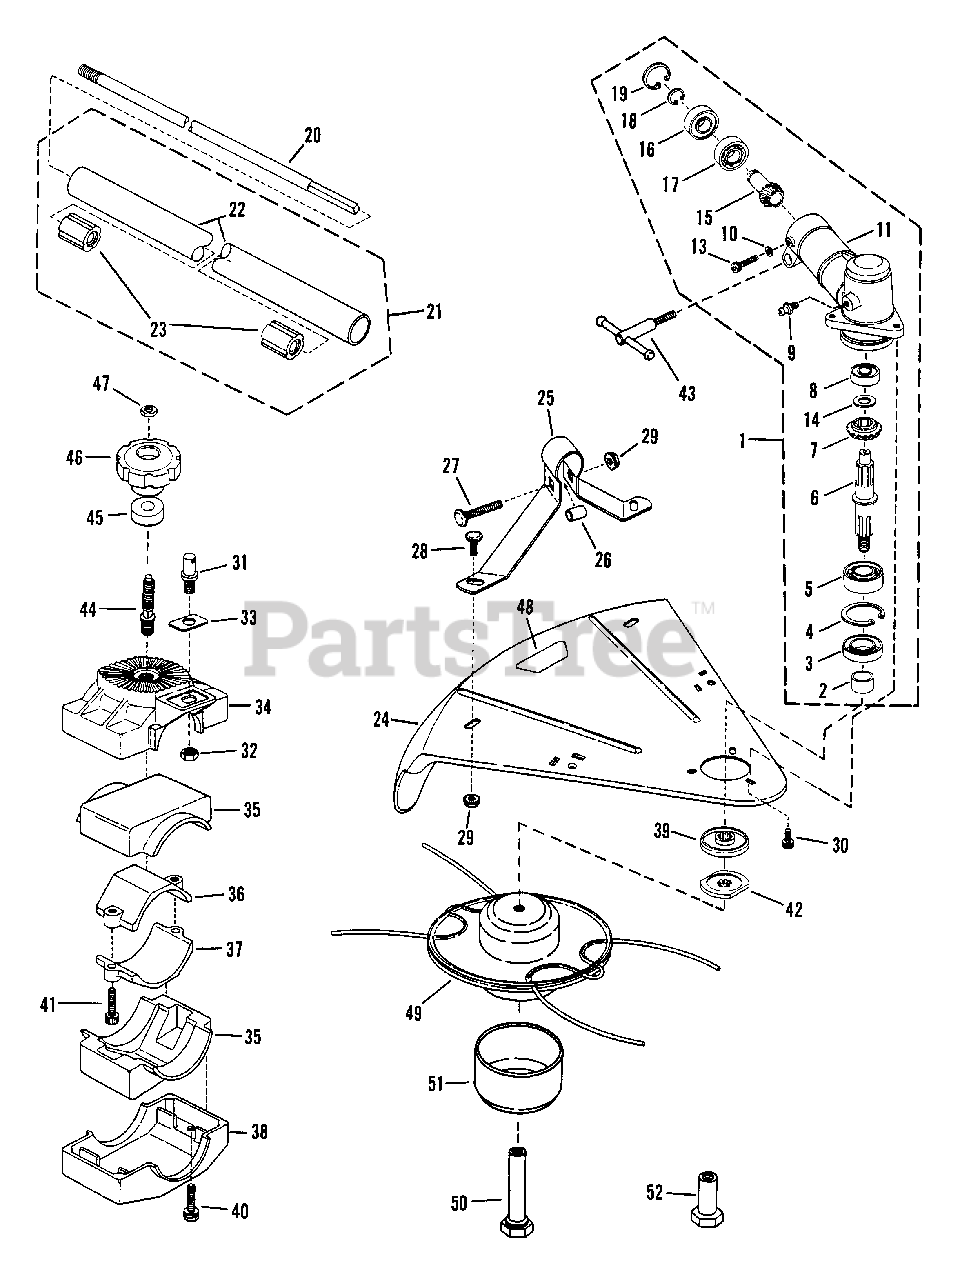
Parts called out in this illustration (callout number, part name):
1	ASSEMBLY, Gear Head
2	SLEEVE, Spline
3	SEAL, Oil
4	RING, Snap 35mm
5	BEARING
6	SHAFT, Spline
7	GEAR, Bevel
8	BEARING
9	FITTING, Lube
11	CASE, Gear
12	BOLT, M6x20mm Socket
13	BOLT, M5x15mm Socket
14	WASHER, Thrust
15	PINION, Bevel
16	BEARING
17	BEARING
18	RING, Snap
19	RING, Snap 26mm
20	SHAFT, 5/16 Drive
21	ASSEMBLY, Tube 8 Bushing
22	TUBE, Main
23	BUSHING
24	SHIELD, Steel
25	BRACE, Shield
26	SPACER, 7/16x1"
27	BOLT, 5/16-18x1-1/2 Short Neck Carriage
28	BOLT, 5/16-18x1/2 Short Neck Carriage
29	NUT, 5/16-18 Hex Flange Lock
30	SCREW, M5x10mm Hex
31	PIN, Guide
32	NUT,3/8-24 Hex Flange Lock
33	PLATE, Mounting Pin
34	JOINT "D", Handle
35	RUBBER, Vibro
36	CLAMP "A", Tube
37	CLAMP "8", Tube
38	JOINT "C", Handle
39	HOLDER "A"
40	SCREW, M6x30mm, Cross Hex Head
41	SCREW, M6x1mm, Socket Hex Head
42	HOLDER "B"
43	T-BOLT, M6
44	BOLT, Latch
45	SPACER, Knob
46	KNOB, Torque
47	NUT, Self-Threader
48	LABEL, Direction
49	HEAD, Fixed Line
50	BOLT, Arbor
51	BALL, Glide
52	ARBOR, Bolt/Blade (Blade Use Only)
53	NUT, M10x1.25Hex Lock (Left Thread) (Blade Use Only)
